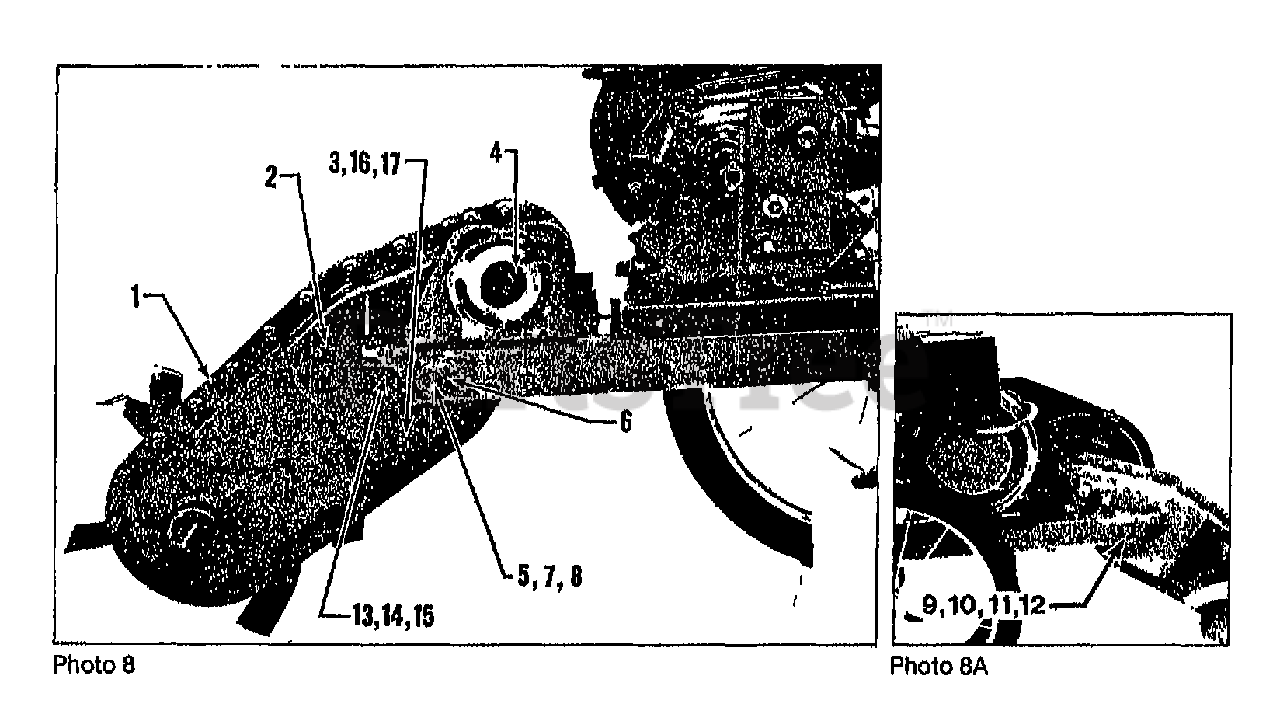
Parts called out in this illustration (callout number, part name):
1	CHAINCASE-CULT PLUS (INCL. DRIVE GUARD MOUNTING BRACKET)
2	PLUG-OIL FILL 3/4-10
3	SCR-SLRH 5/16-18 X .5
4	SEAL-OIL
5	SCR-HH 1/4-20X1.0
6	PLUG-# POSITIONING
7	WASHER-LK .25 ZP
8	NUT-HEX 1/4-20 ZP
9	SCR-HH 1/4-20X1.0
10	SPACER-.745X.281X.37
11	WASHER-LK .25 ZP
12	NUT-HEX 1/4-20 ZP
13	BOLT-HH 5/16-18X3 G5 ZP (ATTACHES CHAIN CASE TO TINE ATTACHMENT)
14	WASHER-LK .312 ZP
15	NUT-HEX 5/16-18 ZP
16	WASHER-.63X.312X.063 RUBBER
17	WASHER-FLAT 5/16 SAE
